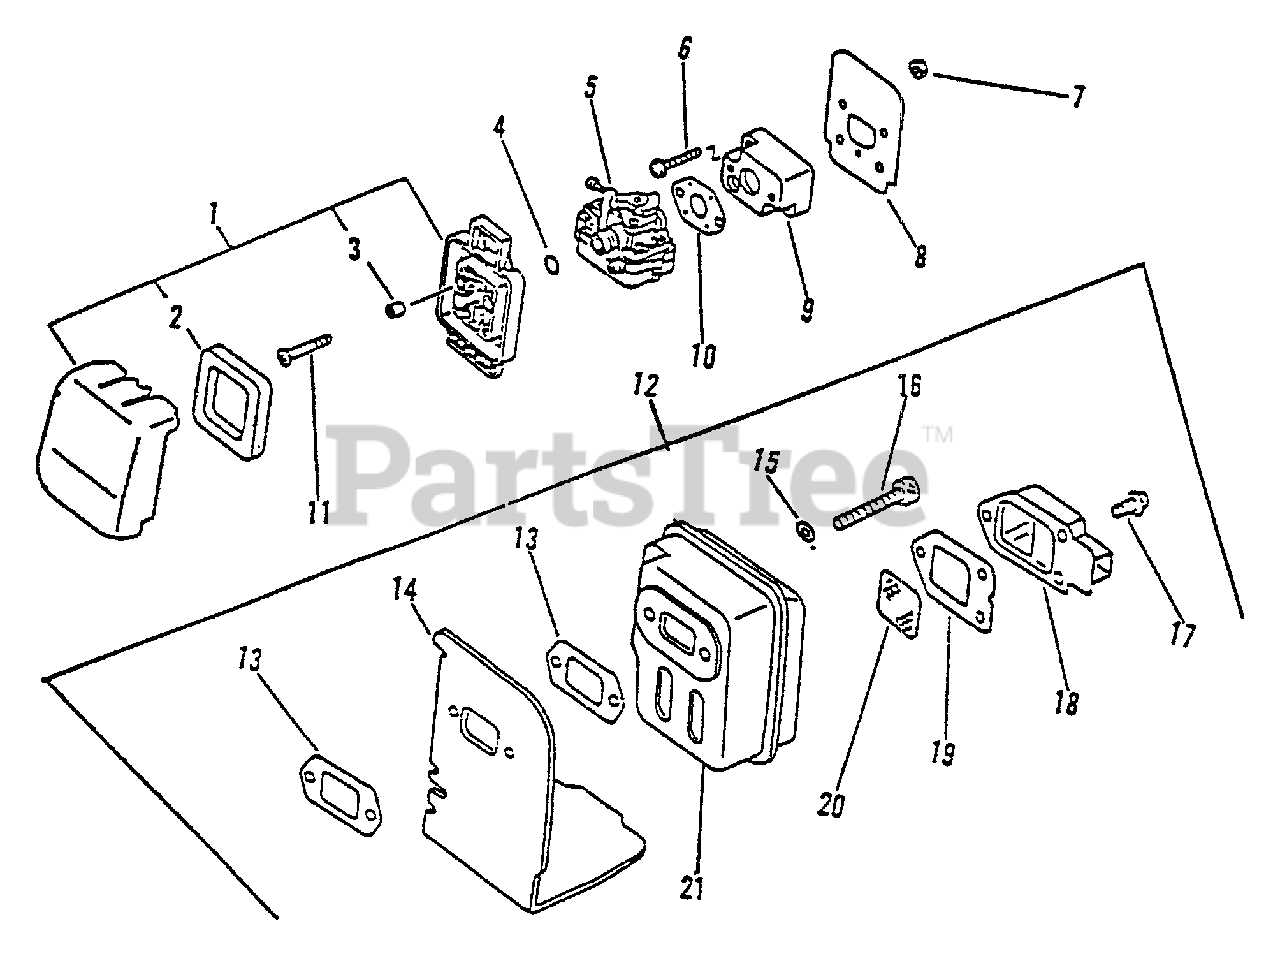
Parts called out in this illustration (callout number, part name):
1	AIR CLEANER ASSY
2	FILTER, AIR
3	SLEEVE
4	O-RING - 15
5	CARBURETOR WYL-10
6	SCREW - 5X22
8	SHIELD, INTAKE
9	INSULATOR, INTAKE
10	GASKET, INTAKE
11	SCREW - 5X64
12	MUFFLER ASSY
13	GASKET, EXHAUST
14	COVER, EXHAUST
15	WASHER - 5
16	SCREW - 5X55
17	SCREW - 4X10
18	GUIDE, EXHAUST - OUTER
19	GASKET, EXHAUST
20	SCREEN, SPARK ARRESTOR
